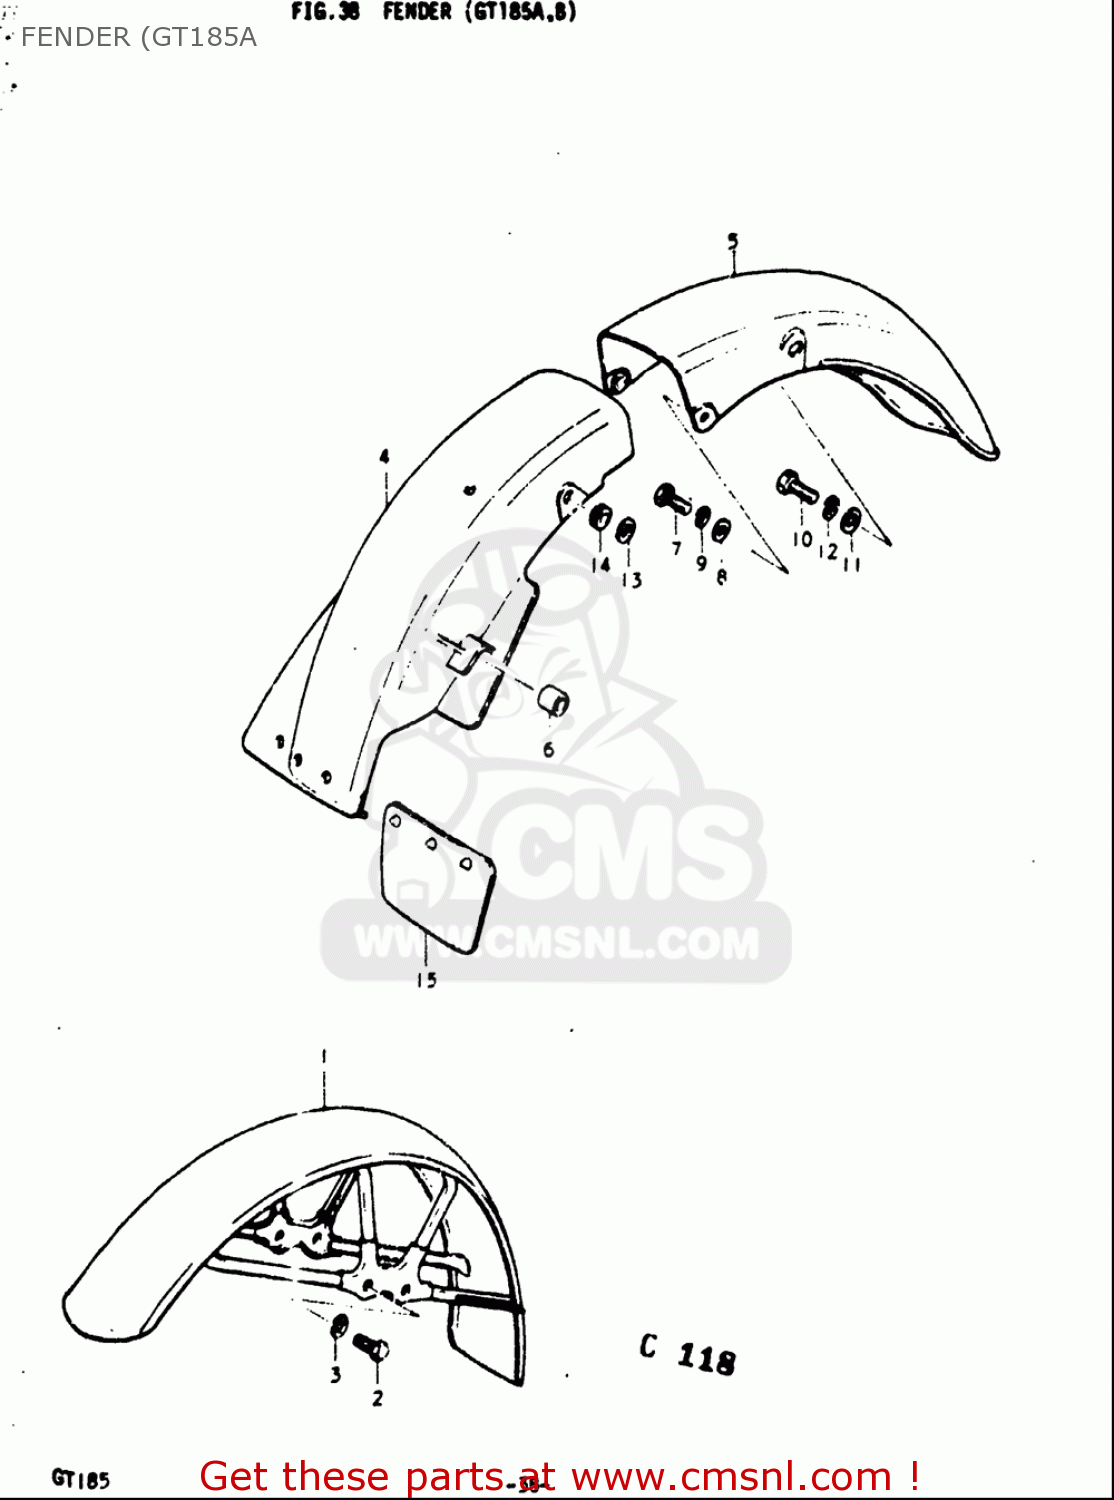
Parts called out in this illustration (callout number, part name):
2	BOLT
3	WASHER,LOCK
6	CUSHION
7	BOLT
8	WASHER
9	WASHER,LOCK
10	BOLT
11	WASHER
12	WASHER,LOCK
13	WASHER(6.5X18X1.6)
14	CUSHION
